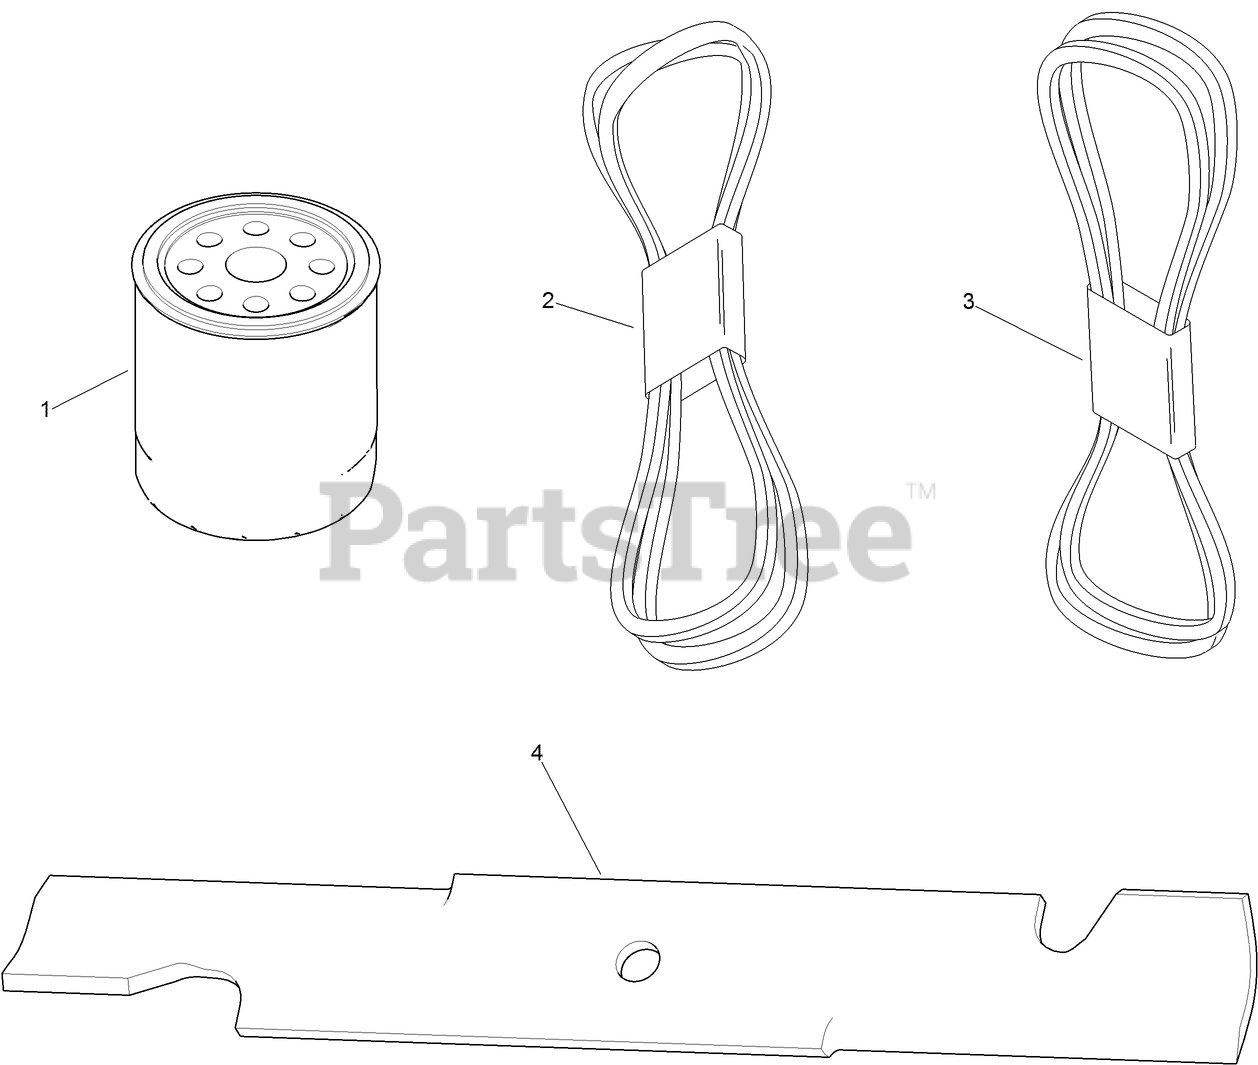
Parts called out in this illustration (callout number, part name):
1	ELEMENT-FILTER, 25 MICRON
2	BELT-V
3	BELT-V
4	BLADE-18IN, HI FLOW
